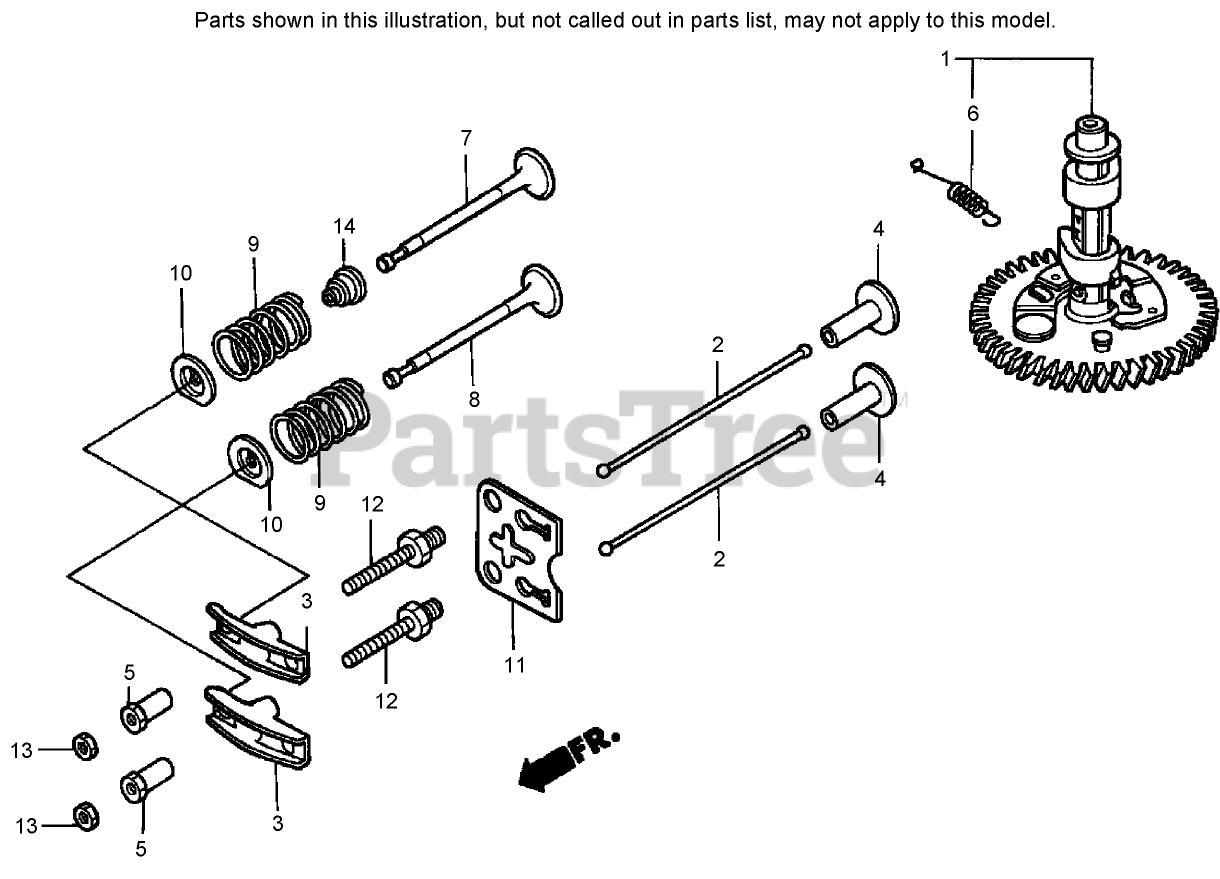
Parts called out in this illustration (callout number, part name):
1	CAMSHAFT ASM
2	ROD-PUSH
3	ARM-ROCKER, VALVE
4	Lifter-Valve
5	PIVOT-ARM, ROCKER
6	SPRING-RETURN, WEIGHT
7	VALVE-INTAKE
8	VALVE-EXHAUST
9	Spring-Valve
10	RETAINER-SPRING, VALVE (INTAKE)
11	Plate-GUIDE, Push Rod
12	BOLT-PIVOT (8 mm)
13	NUT-ADJUSTING, PIVOT
14	SEAL-STEM, VALVE
